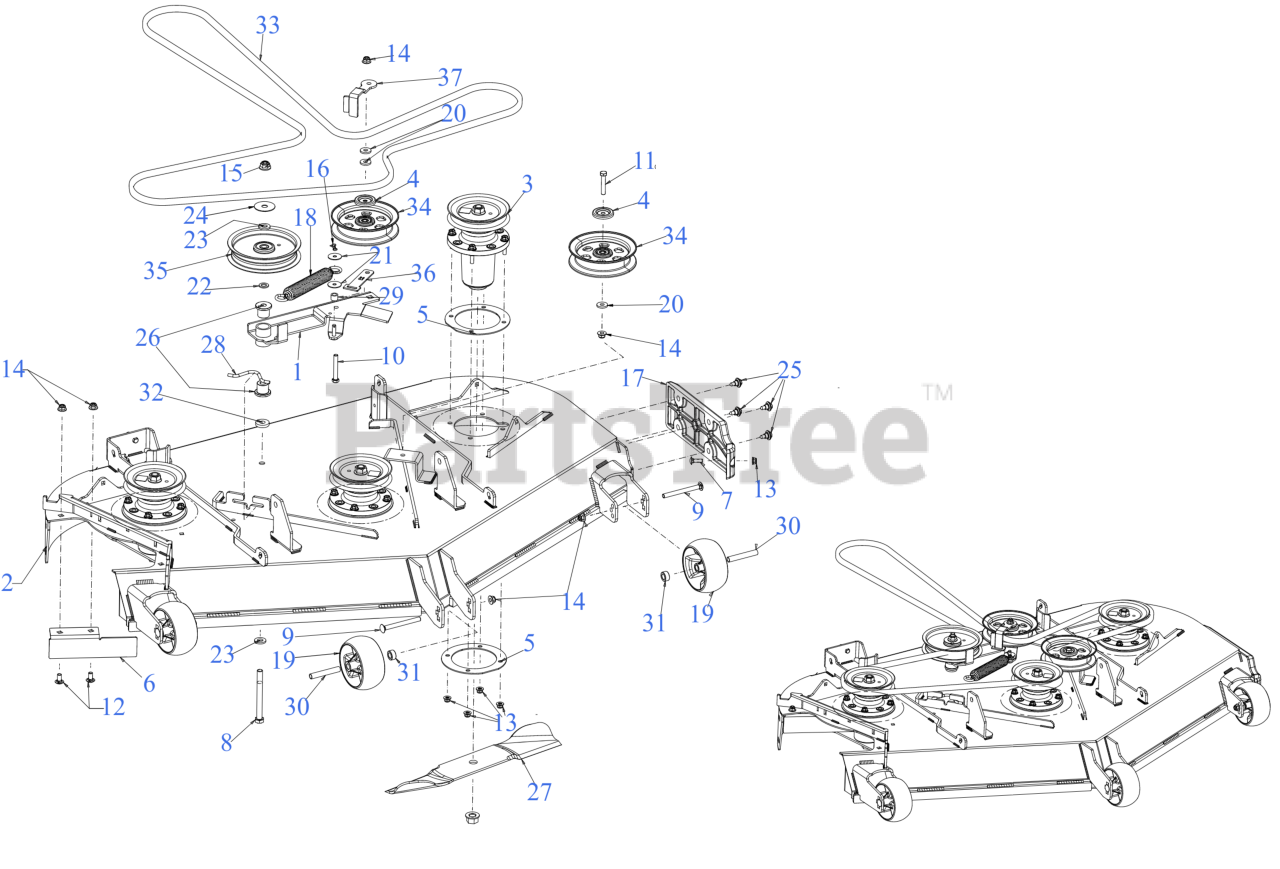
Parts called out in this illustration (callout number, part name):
1	54/60" DECK IDLER ASSEMBLY
2	54" FAB DECK SHELL
3	SPINDLE ASSEMBLY
4	PULLEY CAP 1.875 DIA
5	SPINDLE PLATE
6	54" DECK CHUTE BAFFLE
7	CARRIAGE BOLT 5/16-18 x 1.00
8	BOLT-HEX 1/2-13X5.0 GR5
9	CARRIAGE BOLT 3/8-16 x 4.00 GR5
10	HEX SCREW-3/8-16X2.5 GR5
11	SCREW 3/8-16 x 2.0 GR5
12	CARRIAGE BOLT 3/8-16 x .75
13	FLANGE LOCK NUT 5/16-18
16	BOW TIE COTTER PIN 1/4-5/16
17	DECK SKID PLATE
18	SPRING 1.25" DIA x 8.5" LONG
19	DECK WHEEL
20	FLAT WASHER .385 x 1.00 x .135
21	FLAT WASHER .322 ID x 1.25 x .060
22	FLAT WASHER
23	FLAT WASHER .531X1.060X.134
24	FLAT WASHER
25	SHOULDER SCREW .43X.29X5/16-18 TT
26	FLANGE BEARING
28	DECK SPRING HOOK
30	SPACER .38X.49X3.05LG
31	SPACER-.505 1D
32	SPACER PLATE
33	V-BELT B SEC x 148.25
34	5" FLAT IDLER PULLEY
35	IDLER PULLEY 6.0"
36	BELT KEEPER
37	54/60" IDLER KEEPER
